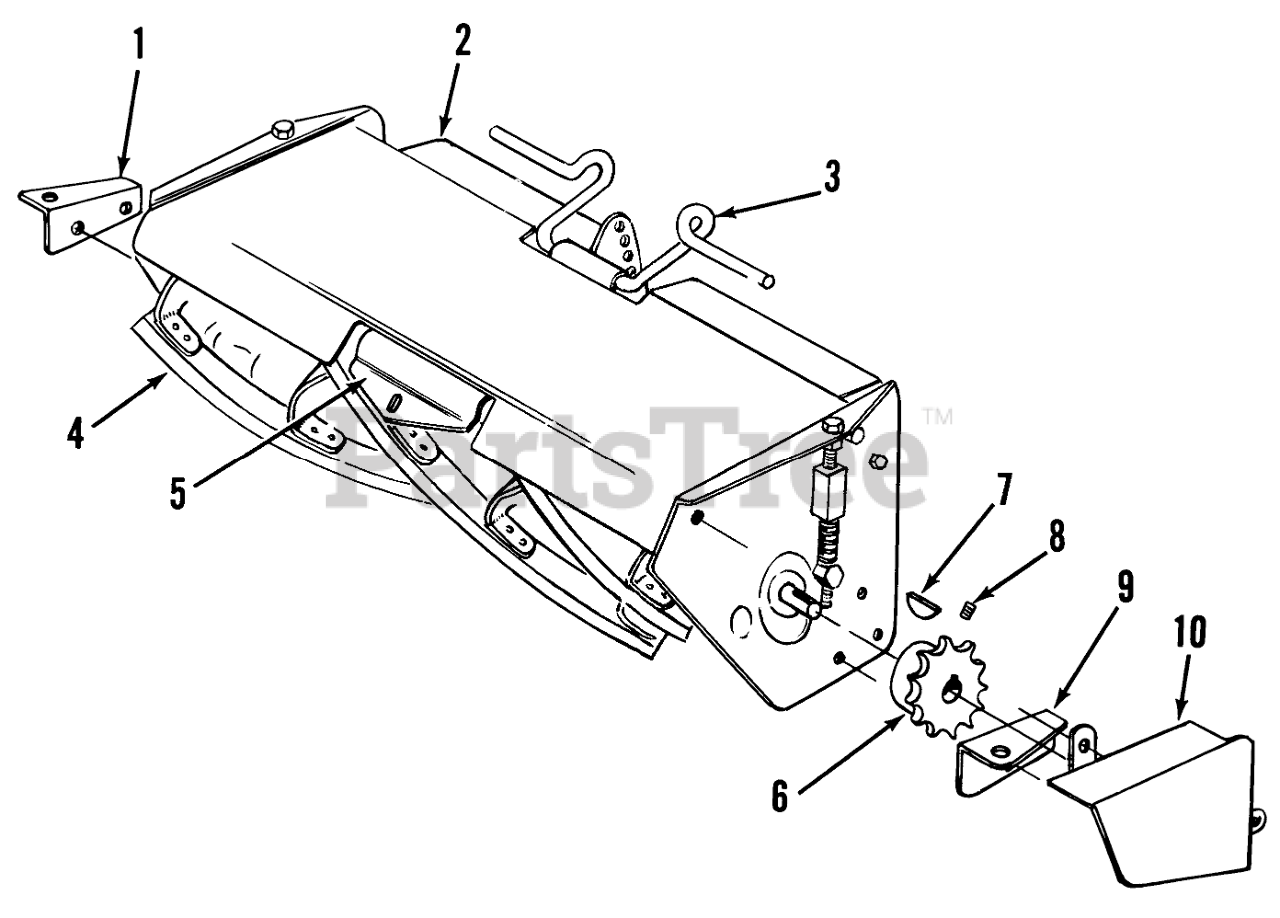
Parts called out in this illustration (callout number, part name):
1	Hanger, Right Hand
7	KEY-WOODRUFF
8	SCREW-HSH
9	Hanger, Left Hand
